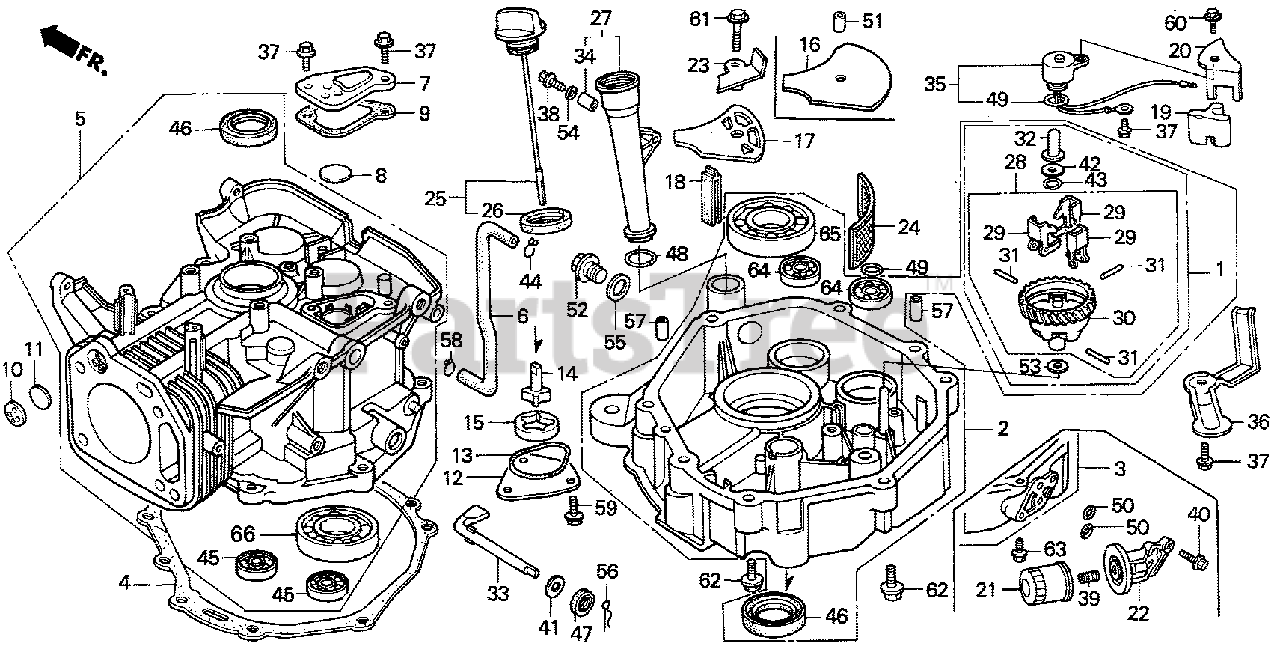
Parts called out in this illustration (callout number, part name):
1	GOVERNOR KIT
2	PAN ASSY., OIL
4	GASKET, OIL PAN (Honda Code 2278166). (NOT AVAILABLE)
4	GASKET, OIL PAN
5	CYLINDER ASSY.
6	TUBE, BREATHER
7	CAP, BREATHER CHAMBER
8	VALVE, BREATHER
9	GASKET, BREATHER CAP
10	PLATE, ONE-WAY VALVE
11	VALVE, ONE-WAY
12	COVER, OIL PUMP
13	O-RING, PUMP COVER
14	ROTOR (INNER)
15	ROTOR, OIL PUMP (OUTER)
17	PLATE, OIL FILTER
18	RUBBER, OIL RETURN
19	STOPPER, OIL
20	PLATE, OIL STOPPER
23	PLATE, SUCTION
24	SCREEN, OIL FILTER
25	CAP ASSY., OIL FILLER
26	GASKET, OIL FILLER CAP
27	EXTENSION, OIL FILLER
28	GOVERNOR ASSY.
29	WEIGHT, GOVERNOR
30	HOLDER, GOVERNOR WEIGHT
31	PIN, GOVERNOR WEIGHT
32	SLIDER, GOVERNOR
33	SHAFT, GOVERNOR ARM
34	COLLAR, EXTENSION
35	SWITCH, OIL LEVEL
36	PROTECTOR, SWITCH
37	BOLT, FLANGE (6X12) (CT200)
38	BOLT, FLANGE (6X35)
41	WASHER, THRUST (8.1MM)
42	WASHER (6X16)
43	CLIP, GOVERNOR HOLDER
44	CLIP, TUBE
45	BEARING, RADIAL BALL (6202)
46	OIL SEAL (35X52X8)
47	OIL SEAL (8X14X5)
48	O-RING (22.5X2.2)
49	O-RING (11.8X2.4)
52	BOLT, DRAIN PLUG (20MM)
53	WASHER, PLAIN (6MM)
54	WASHER, PLAIN (6MM)
55	WASHER, DRAIN PLUG (20MM)
56	PIN, LOCK (8MM)
56	PIN, LOCK (10MM)
57	PIN, DOWEL (8X12)
57	PIN A, DOWEL (8X12)
58	CLIP, TUBE (C11)
59	BOLT, FLANGE (6X12)
60	BOLT, FLANGE (6X16)
61	BOLT, FLANGE (6X25)
62	BOLT, FLANGE (8X40)
62	BOLT, FLANGE (8X60)
64	BEARING, RADIAL BALL (6202)
65	BEARING, RADIAL BALL (6207)
66	BEARING, RADIAL BALL (6207)
